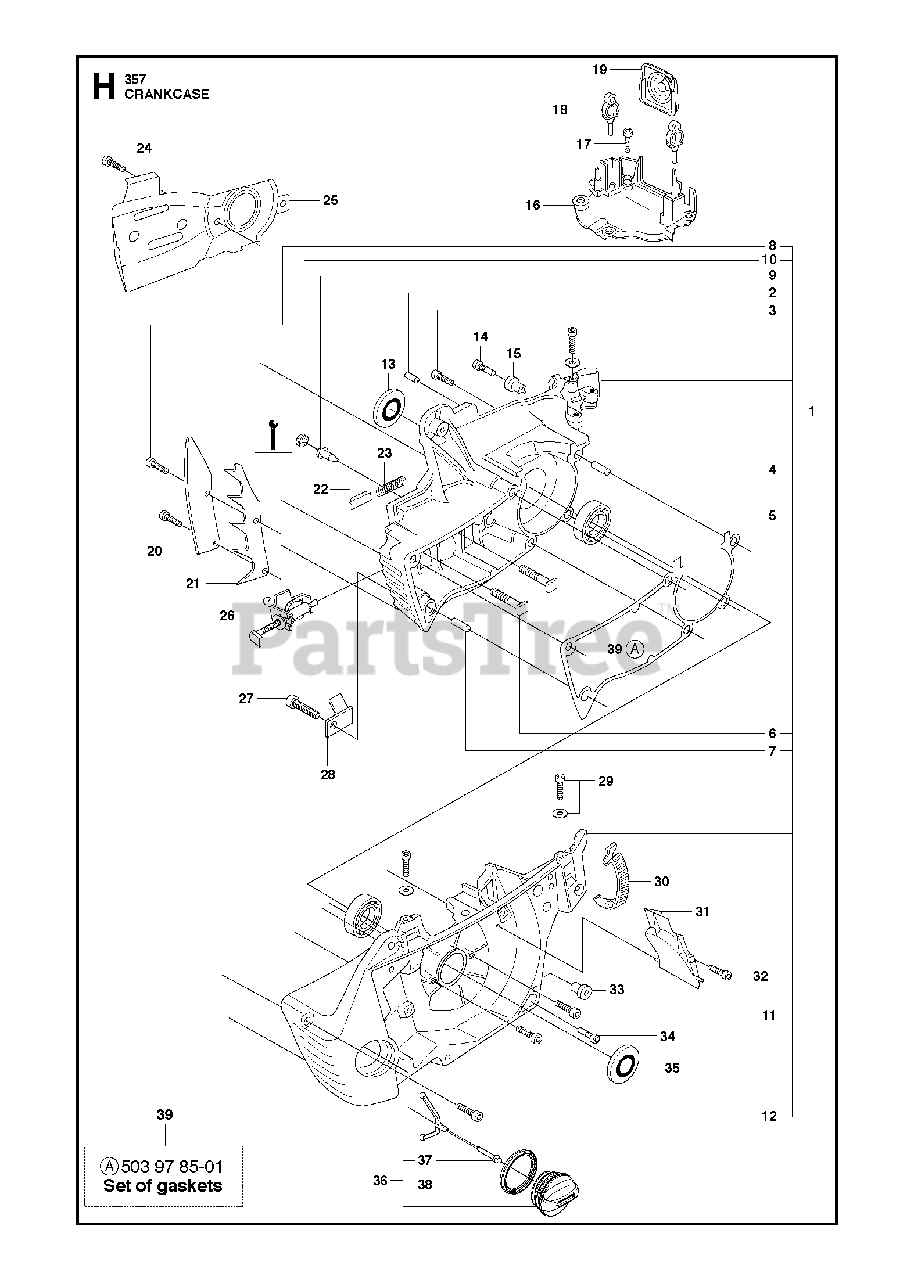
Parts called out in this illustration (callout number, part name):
1	CRANKCASE ASSY
2	PIN
3	SCREW
4	SLEEVE
5	BALL BEARING-6202-C3 SKF
6	BOLT
7	SLEEVE
8	SCREW
9	VALVE-CHECK (DUCKBILL)
10	PLUG
11	SCREW
12	SCREW
15	MOVEMENT LIMITER
18	SUPPORT
21	FELLING DOG
23	LOCK SPRING
26	CHAIN TENSIONER
28	CHAIN CATCHER
30	BUCKLE ORANGE
33	MOVEMENT LIMITER
36	TANK CAP
37	TANK LOCK
38	SEALING
39	GASKET SET
